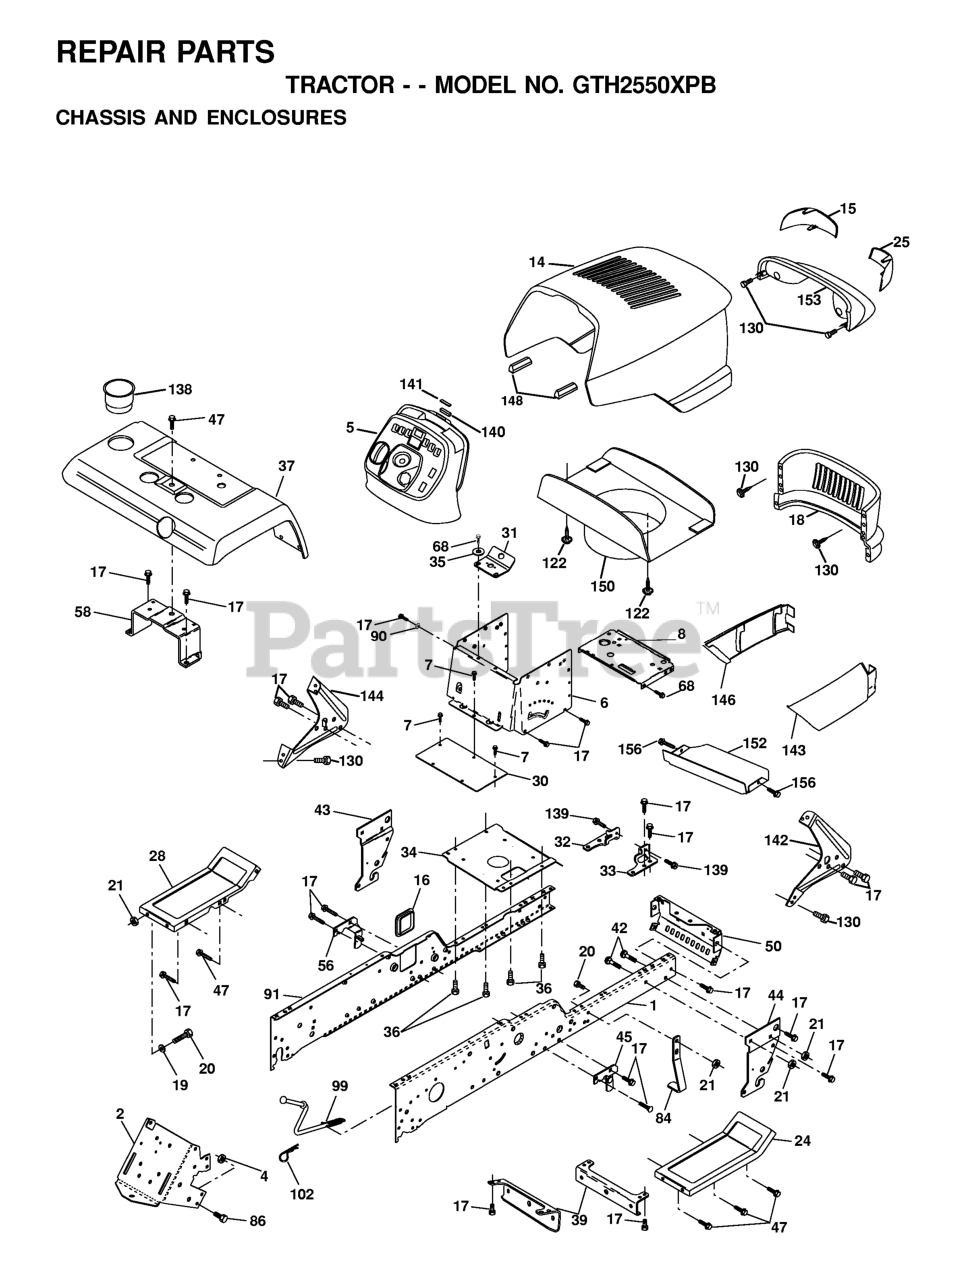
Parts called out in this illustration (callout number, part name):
2	DRAWBAR, GT
4	Nut, Lock Hex 7/16 Unc
5	DASH.STEALTH.YTGT.2CYL.BLK
6	DASH VGT, LOWER
7	SCREW
8	SUPPORT, BATTERY
14	HOOD ASM.
15	LENS RH
16	COVER ACCESS
17	SCREW 3/8-16X3/4
18	GRILLE
19	WASHER
20	BOLT
24	FOOTREST RH
25	LENS LH
28	FOOT REST LH
30	SADDLE.HYDRO.95
31	BRACKET SUPT 1-PC VGT STEERING
34	PLATE ASM ENG CHASSIS
35	WASHER
36	SCREW 5/16"
39	BRACKET AXLE, FRONT
42	BOLT D
43	FRONT SUSPENSION BRKT LH
44	FRONT SUSPENSION BRKT RH
45	BRACKET SUSP RH
47	SCREW 3/8-16X1/2
50	BRACKET, CHASSIS FRONT
56	BRACKET ASM, SUSP CHASSIS
58	BRACKET ASM, FENDER
68	Screw 5/16-18 x 1/2 Hex, Self Tapping 5/16-18 x 1/2
84	MOWER STOP
86	BOLT
90	LOCKWASHER
99	ROD ASM, BYPASS
102	RETAINER M
122	SCREW.HEX.WS.HD.8-18 X 7/8
130	SCREW
139	BOLT, SHOULDER 5/16-18
140	MAGNET STEALTH
141	STRIKER PLATE
142	BRACKET DASH STEALTH(R)
143	SKIRT GRILLE RH
144	BRACKET DASH STEALTH LH
146	SKIRT GRILLE LH
148	EXTRUSION BUMPER (3 2) (2 2)
150	DUCT HEAT HOOD
152	BROWNING SHIELD
156	SCREW 5/16"
